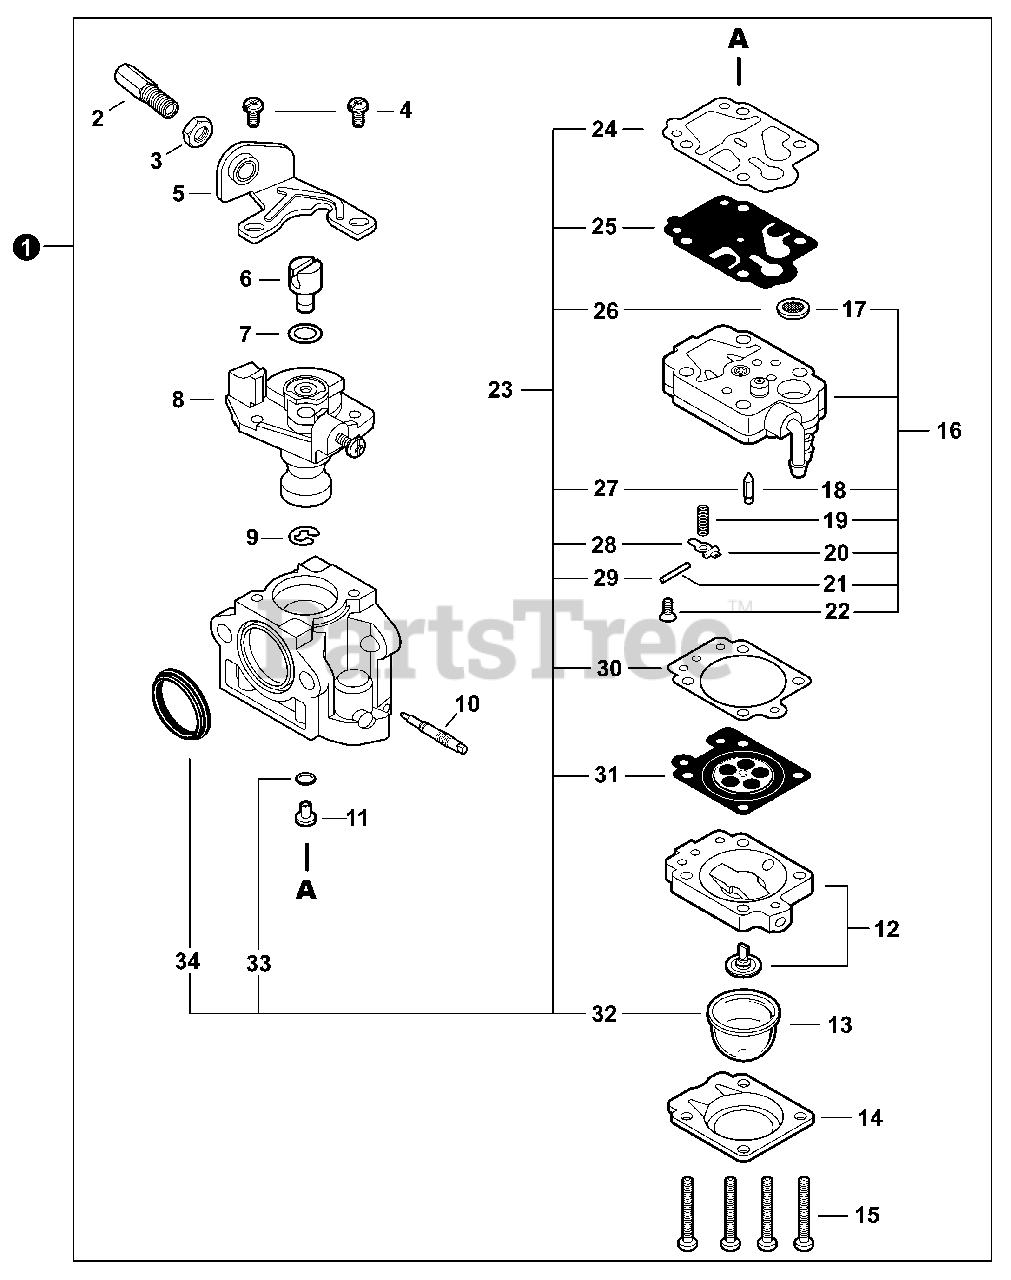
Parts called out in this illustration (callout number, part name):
1	CARBURETOR - WYK-357
2	ADJUSTER, THROTTLE CABLE
3	NUT, ADJUSTER LOCK M7
5	BRACKET, THROTTLE CABLE
8	VALVE ASSY, THROTTLE
10	NEEDLE, HIGH SPEED
11	JET, MAIN #31
12	BODY ASSY, PURGE
13	BULB, PURGE
14	RETAINER, PURGE BULB
16	BODY ASSY, PUMP
17	SCREEN, FUEL INLET
18	VALVE, INLET NEEDLE
19	SPRING, METERING LEVER
20	LEVER, METERING
21	PIN, METERING LEVER
22	SCREW
23	REPAIR KIT, CARBURETOR
24	GASKET, PUMP
25	DIAPHRAGM, PUMP
26	SCREEN, FUEL INLET
27	VALVE, INLET NEEDLE
28	LEVER, METERING
29	PIN, METERING LEVER
30	GASKET, METERING DIAPHRAGM
31	DIAPHRAGM, METERING
32	BULB, PURGE
33	O-RING
34	RING, PACKING
